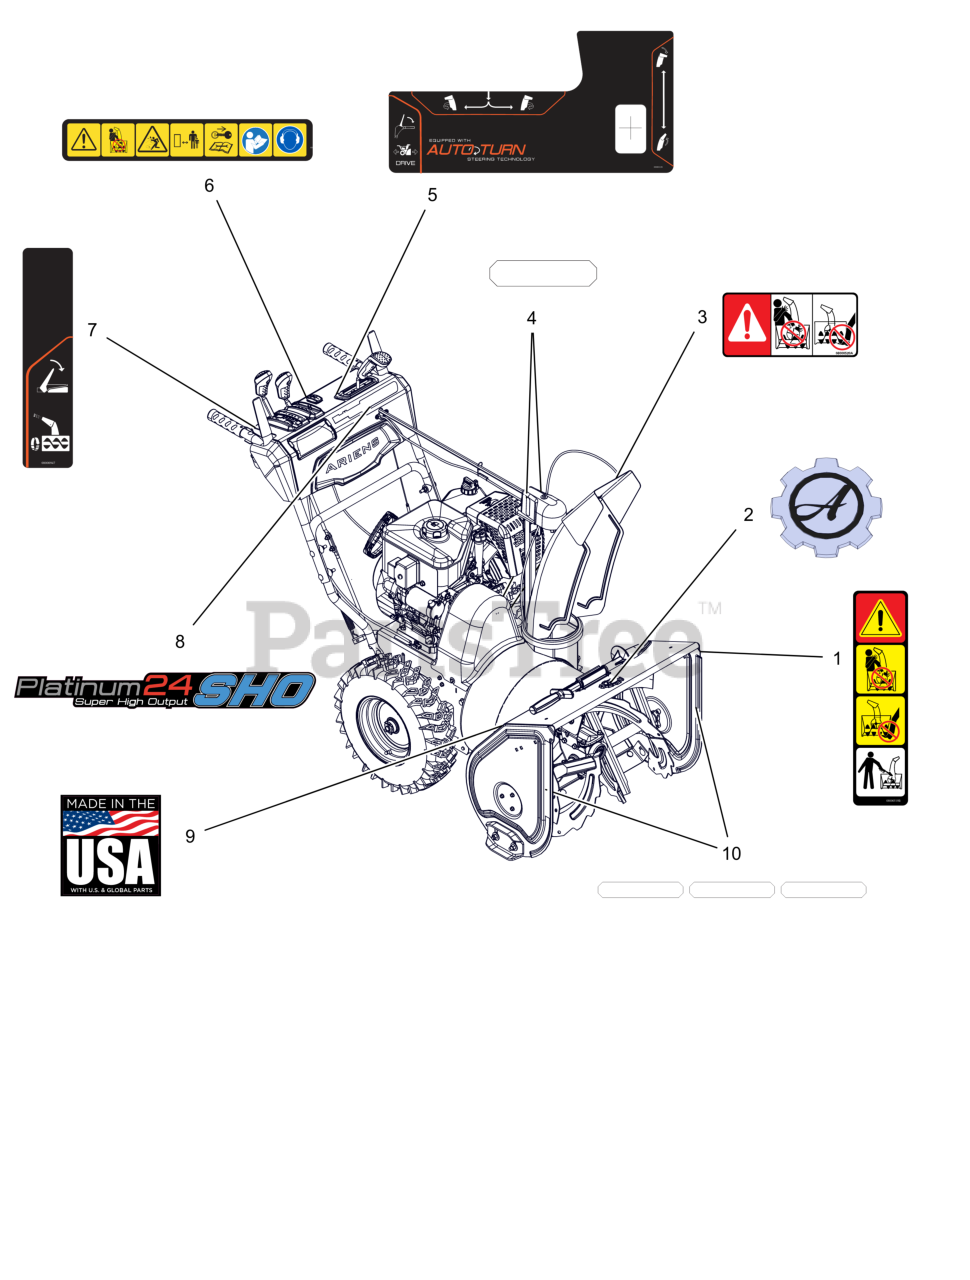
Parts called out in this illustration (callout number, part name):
1	DECAL, DANGER - ROTATING PARTS
2	DECAL, ARIENS - GEAR BADGE
3	DECAL, DANGER
4	DECAL,REFLECTIVE,GEAR COVER
5	DECAL,CONTROL-LG QT2
6	DECAL,DASH - SAFETY
7	DECAL,CONTROL-RH CONTROL
8	DECAL, DASH, PLATINUM 24 SHO
9	DECAL, MADE IN USA
10	DECAL,REFLECTIVE,HOUSING
